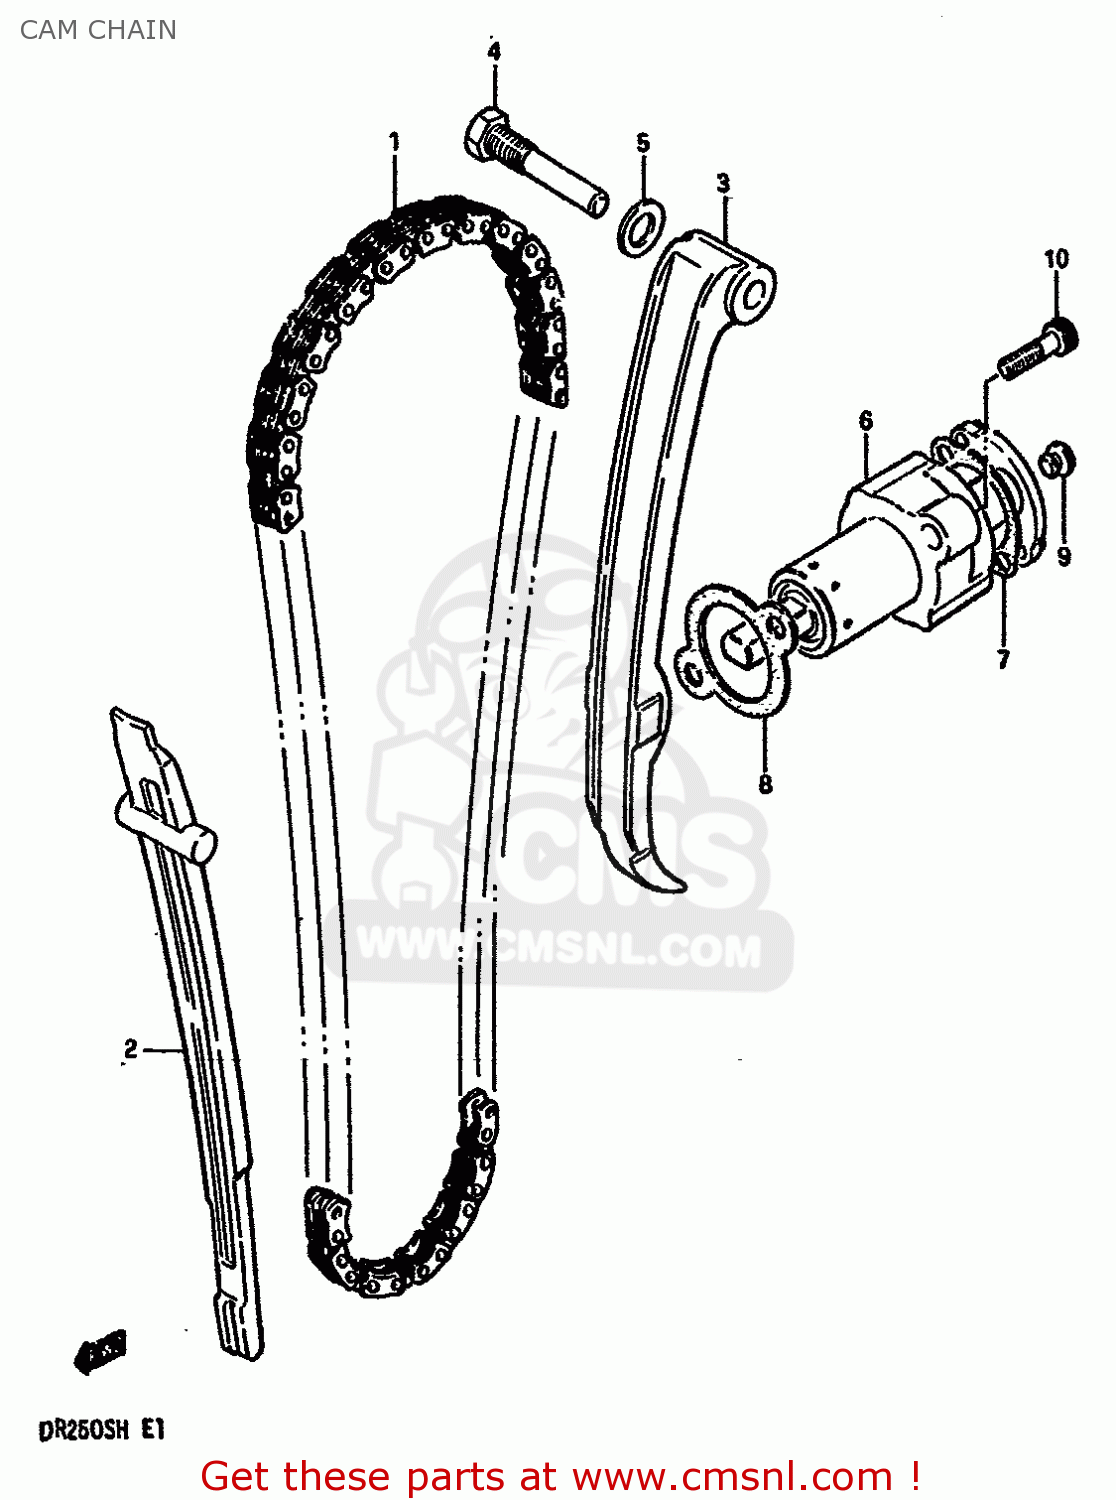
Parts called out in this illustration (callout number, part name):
1	CHAIN,CAMSHAFT DRIVE
2	GUIDE,CAM CHAIN
3	TENSIONER,CAM CHAIN
4	BOLT,CAM CHAIN TENSIONER
5	GASKET 8.2X14X1 (NAS)
6	ADJUSTER ASSEMBLY,TENSIONER
7	GASKET,ADJUSTER CAP (MCA)
8	GASKET,TENSIONER ADJUSTER (NAS)
9	PLUG,ADJUSTER
10	BOLT
